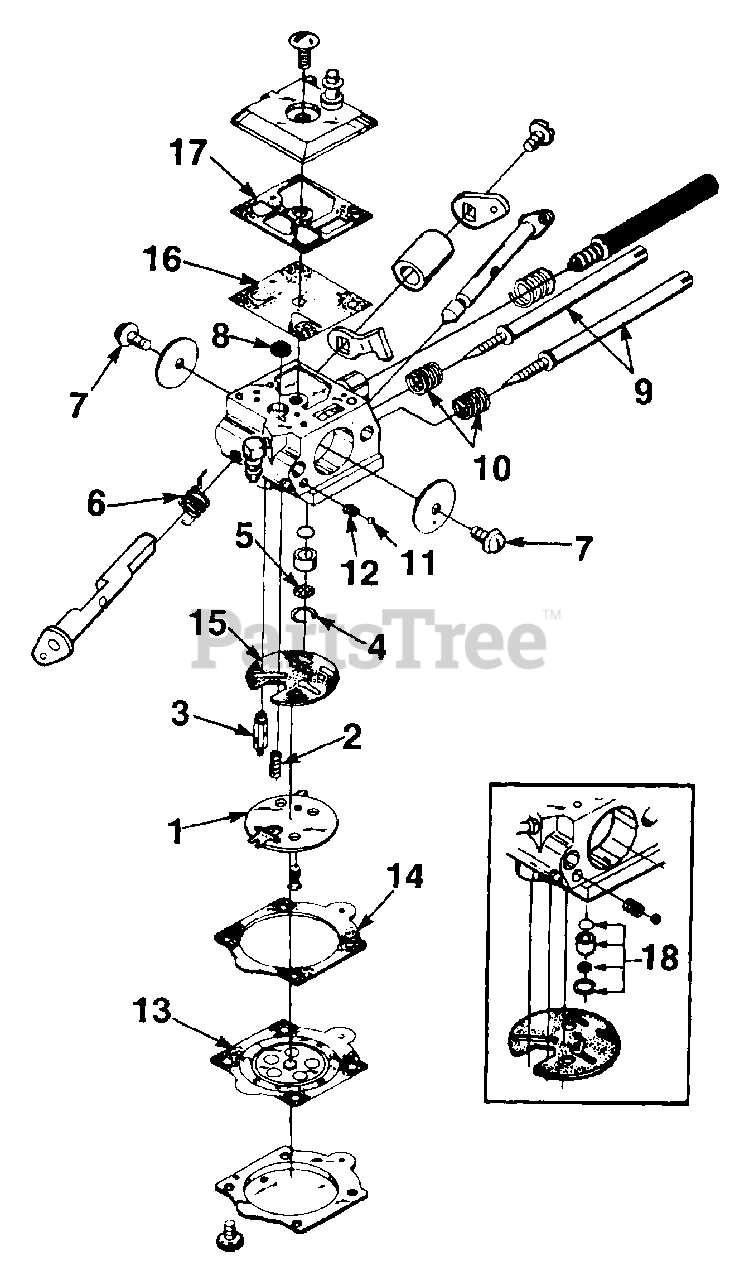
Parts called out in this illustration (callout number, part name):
1	Repair Kit
2	Repair Kit
3	Repair Kit
4	Repair Kit
5	Repair Kit
6	Repair Kit
7	Repair Kit
8	Repair Kit
9	Repair Kit
10	Repair Kit
11	Repair Kit
12	Repair Kit
13	Repair Kit
13	Gasket/Diaphragm kit
14	Repair Kit
14	Gasket/Diaphragm kit
15	Repair Kit
15	Gasket/Diaphragm kit
16	Repair Kit
16	Gasket/Diaphragm kit
17	Repair Kit
17	Gasket/Diaphragm kit
18	Check Valve Repair Kit
